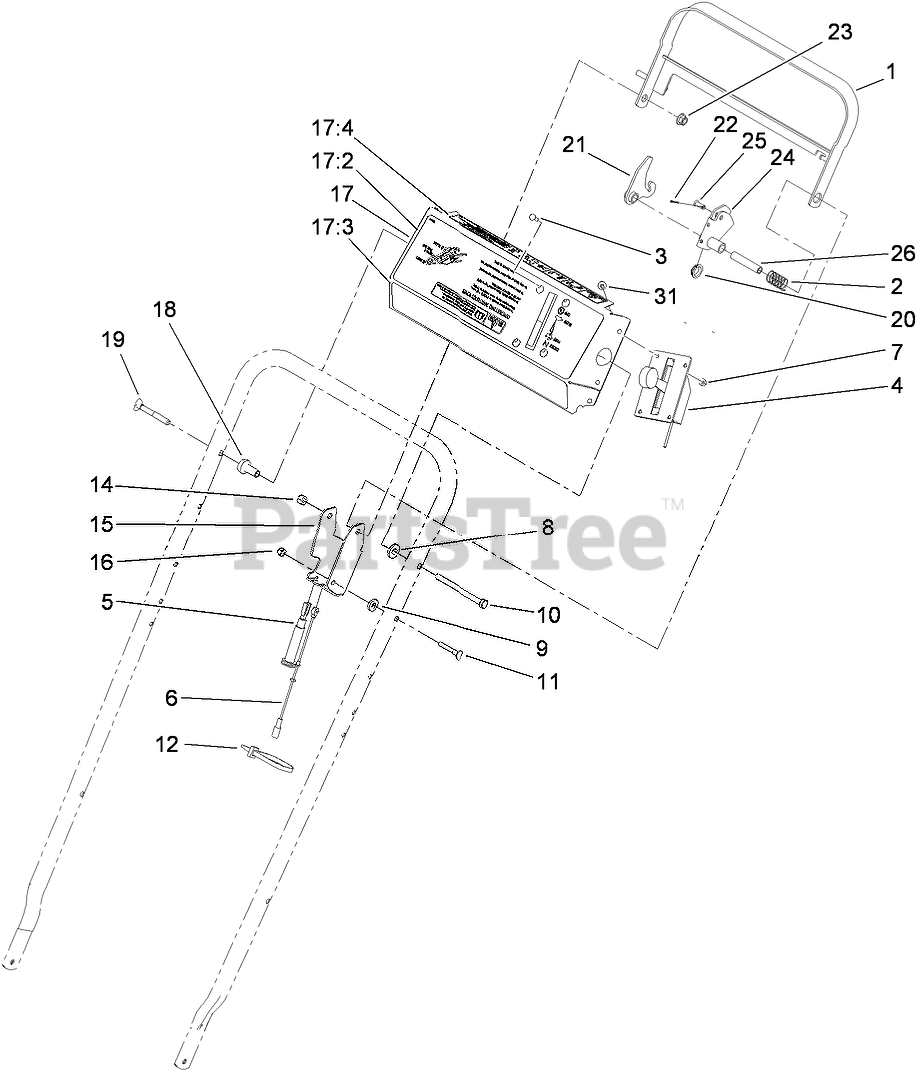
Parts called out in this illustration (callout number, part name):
1	BAR-CONTROL
2	SPRING-CONTROL
3	SCREW-PPH
4	CONTROL-THROTTLE
5	CABLE-TRACTION
6	CABLE-CLUTCH
7	NUT-LOCK, NI
8	SPACER
9	SPACER
10	SCREW-HH
11	SCREW-HANDLE
12	TIE-CABLE
14	NUT-LOCK, NI
15	BRACKET-CONTROL
16	NUT-LOCK, NI
17	PANEL ASM
17:2	DECAL-PANEL
17:3	Decal-Panel
17:4	DECAL-DANGER PANEL
18	SPACER-SUPPORT
19	SCREW
20	BUSHING-FLANGE
21	LEVER-TRACTION
22	PIN-COTTER
23	NUT-LOCK, NI
24	LEVER-BBC
25	PIN-CABLE
26	SPACER-BRACKET, CONTROL
31	SCREW-HWHTF
